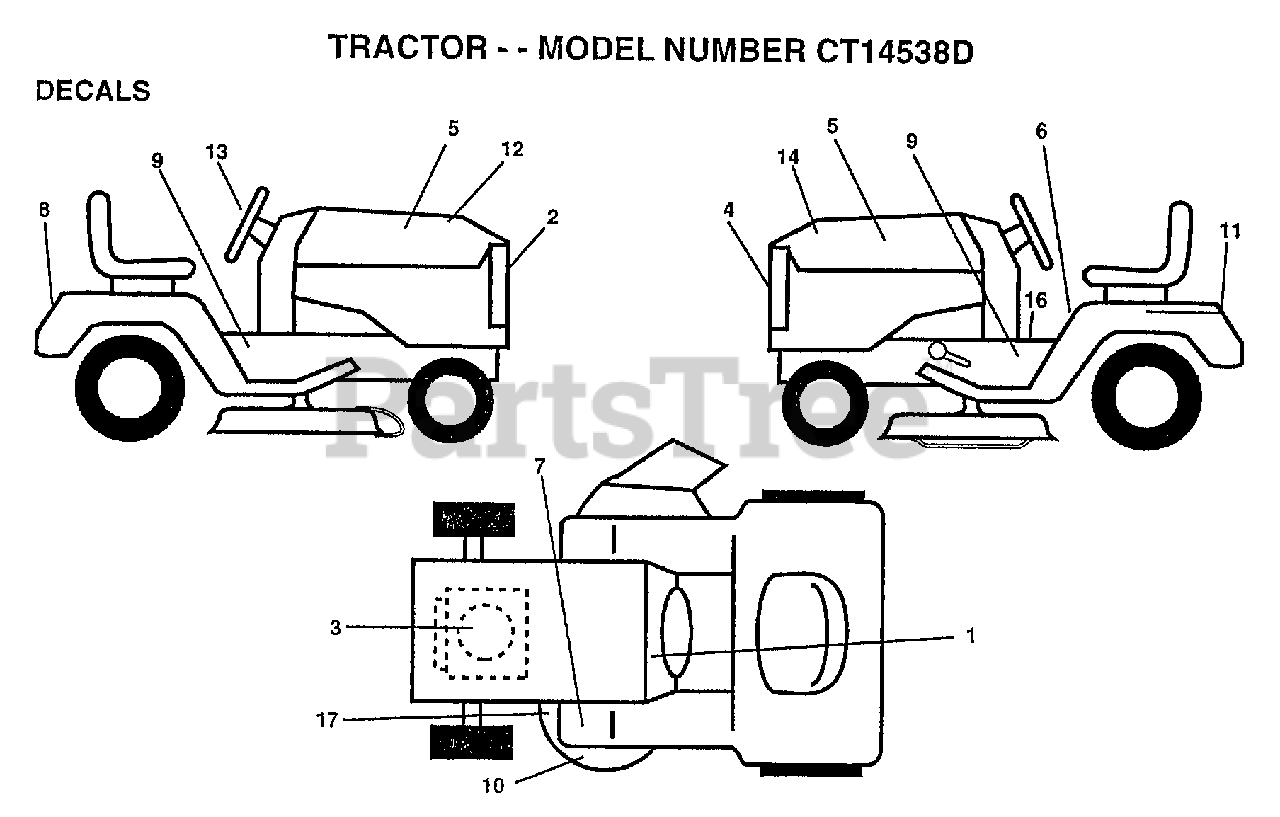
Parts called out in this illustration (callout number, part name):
1	"DECAL-OPER,GEAR D"
2	GRILL DECAL
3	DECAL, ENGINE
5	DECAL.INS.HD.RALL
6	"DECAL DANGER,FEND"
8	FENDER DECAL
11	DECAL.BATRY.3-3908
12	DECAL HOOD RH RLY
13	"DECAL,STR WHL"
14	DECAL HOOD LH RLY
16	DECAL BRAK PARK
17	DECAL
